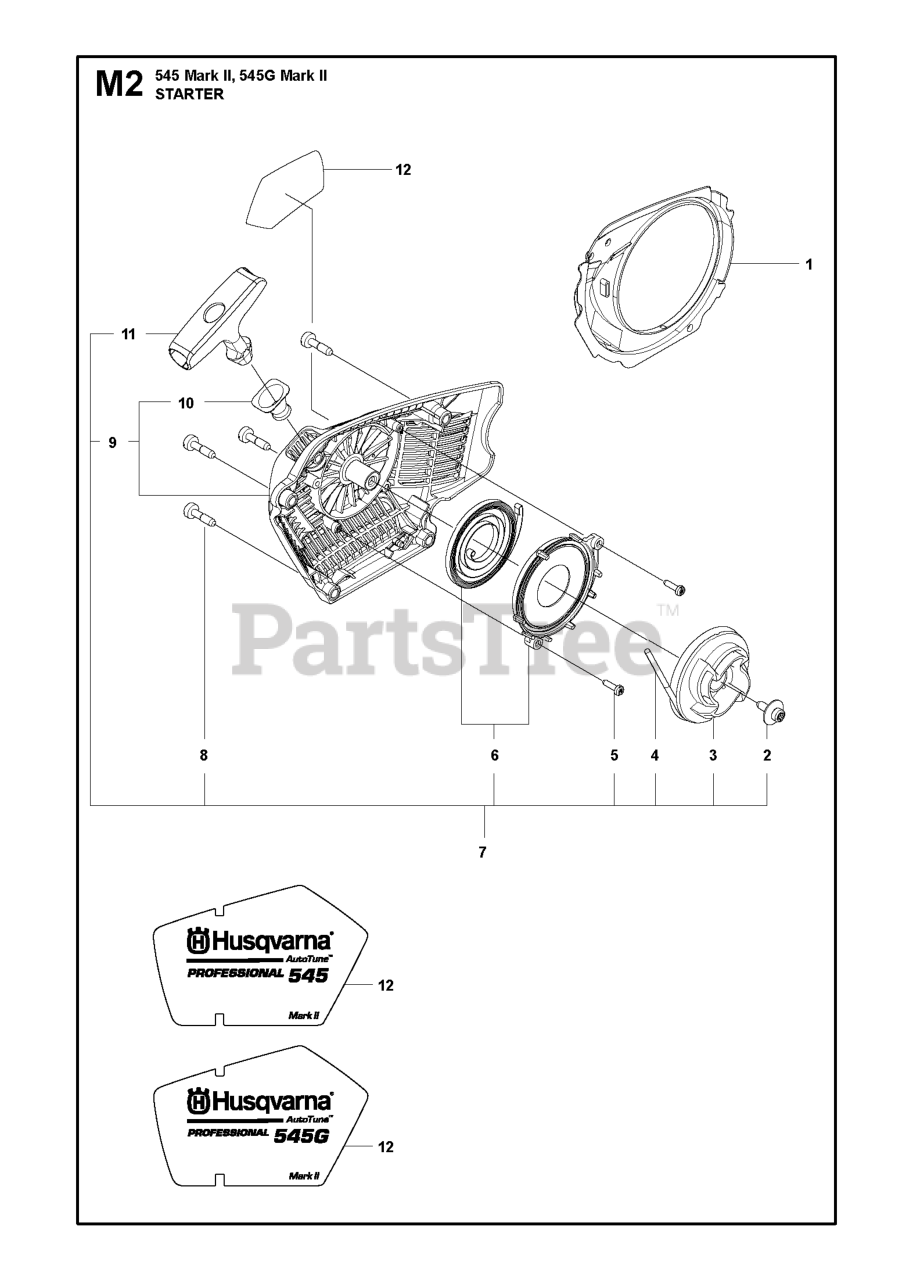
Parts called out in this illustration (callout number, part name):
1	COOLING AIR CONDUCTOR
2	SCREW ITXSCT MT5X16 10.9 TBO
4	STARTER ROPE
5	SCREW CITXPANT
6	SPRING CASSETTE ADDY
7	STARTER ASSY KIT SPARE PART H5
8	SCREW CITXPANMO
9	STARTER HOUSING
12	LABEL
